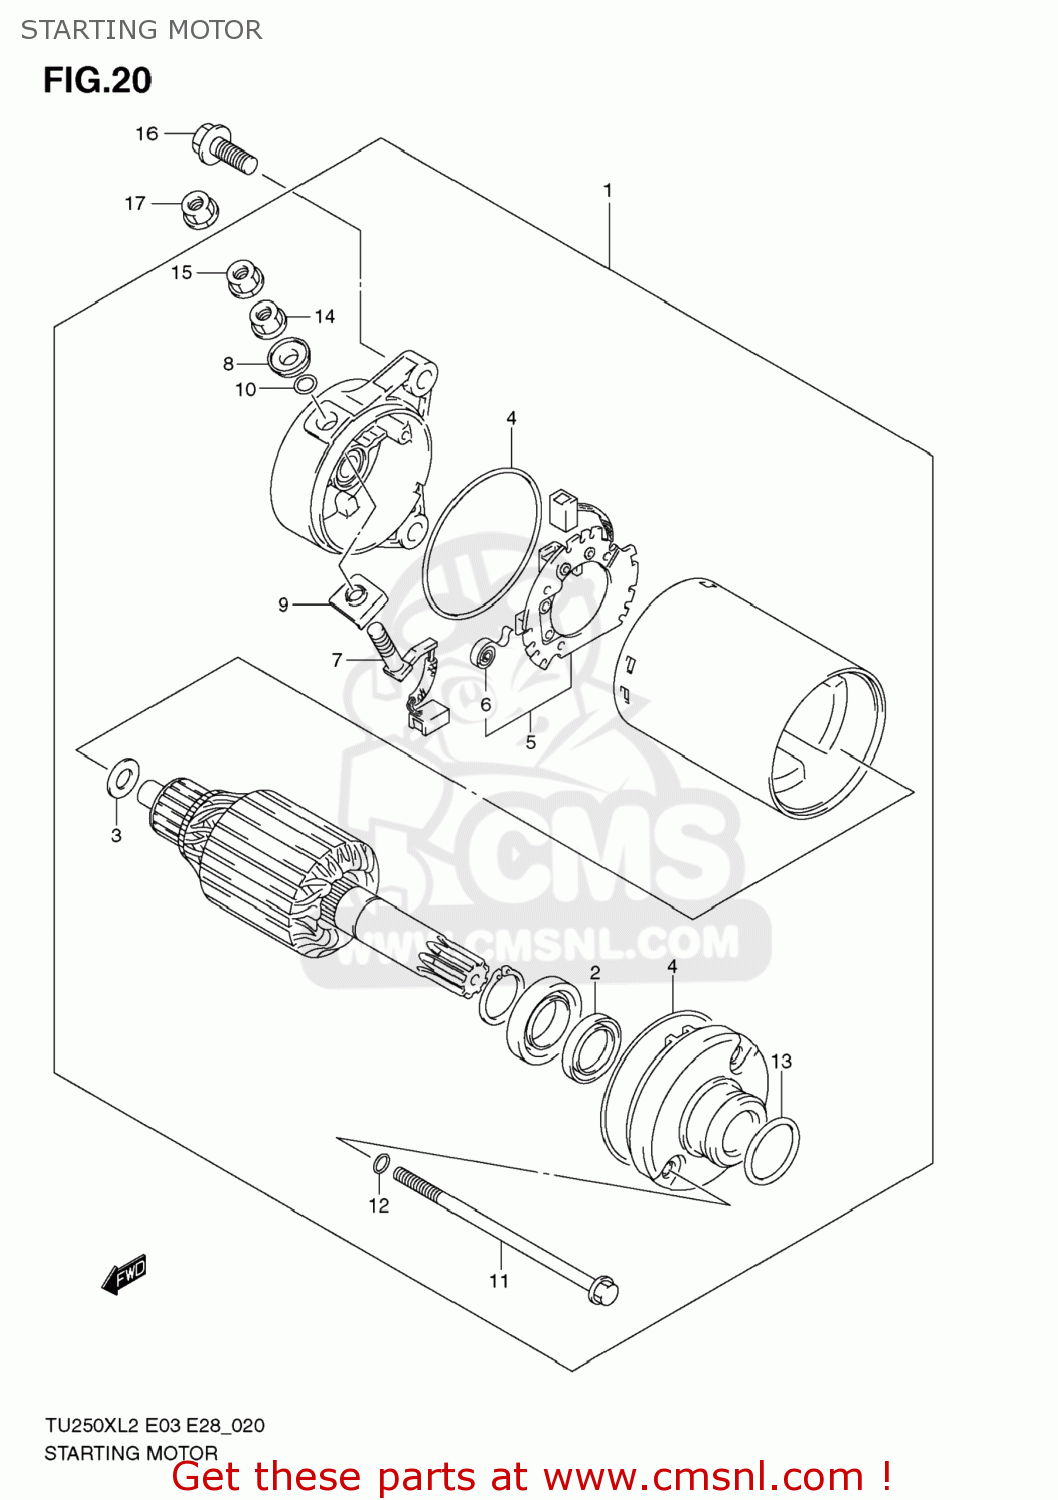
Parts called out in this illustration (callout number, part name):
1	MOTOR ASSY,STARTING
2	SEAL,OIL
3	SHIM SET,STARTING MOTOR
4	O RING
5	HOLDER,BRUSH
6	SPRING
7	BRUSH SUB ASSY,STARTING MOTOR
8	BUSHING
9	BUSH,B
10	O RING
11	BOLT
12	O RING
13	O RING(D:3,ID:24.5)
14	NUT
15	NUT
16	BOLT(6X25)
17	NUT
